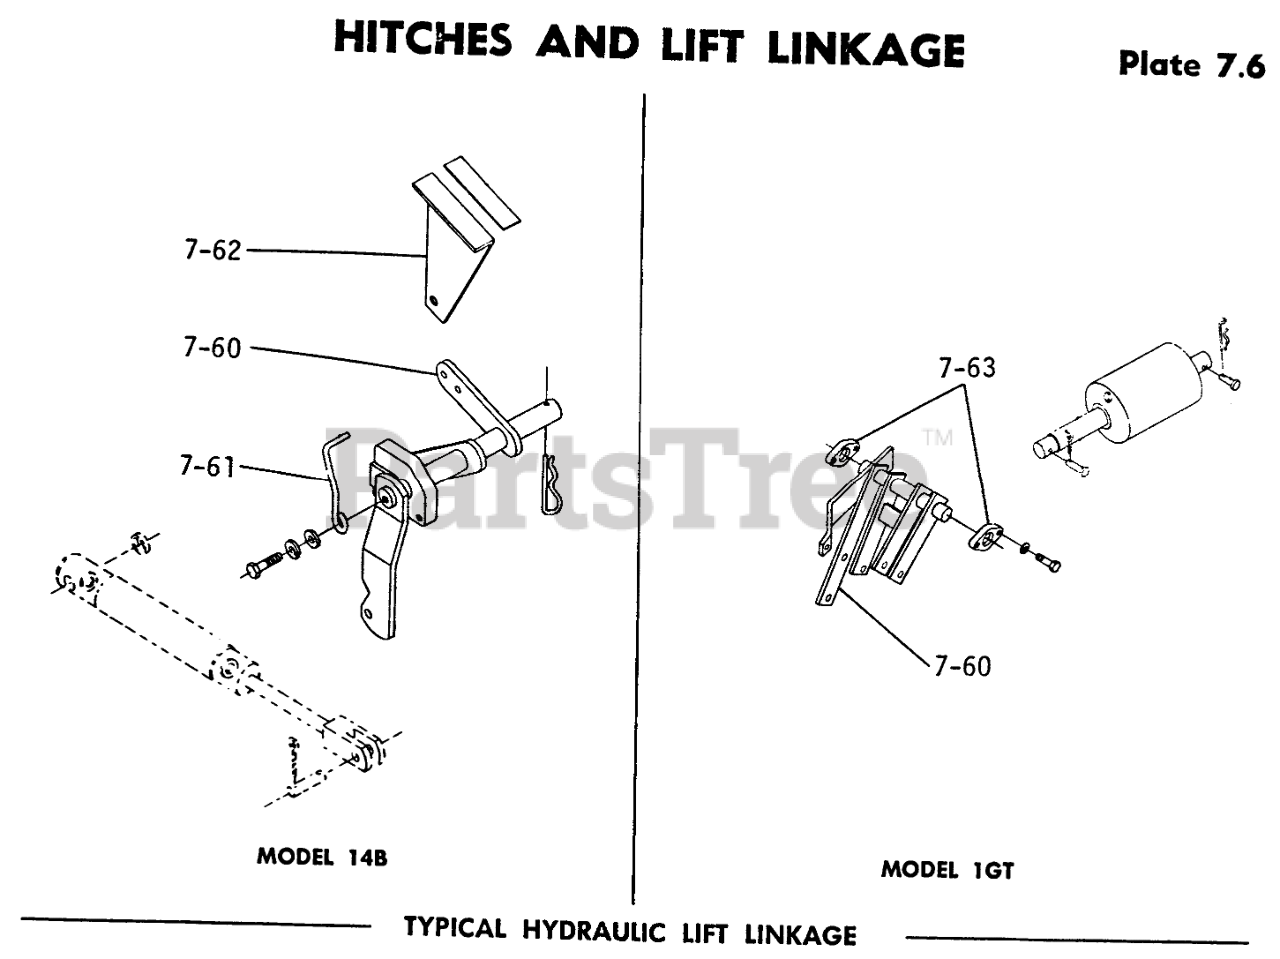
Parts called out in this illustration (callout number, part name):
7-60	Lift Arm
7-61	Arm
7-61	Bolt 5/16-18 x
7-61	Washer
7-61	Lockwasher
7-63	Bolt 3/8-16 x 7/8
7-63	Lockwasher
8-60	Hairpen
